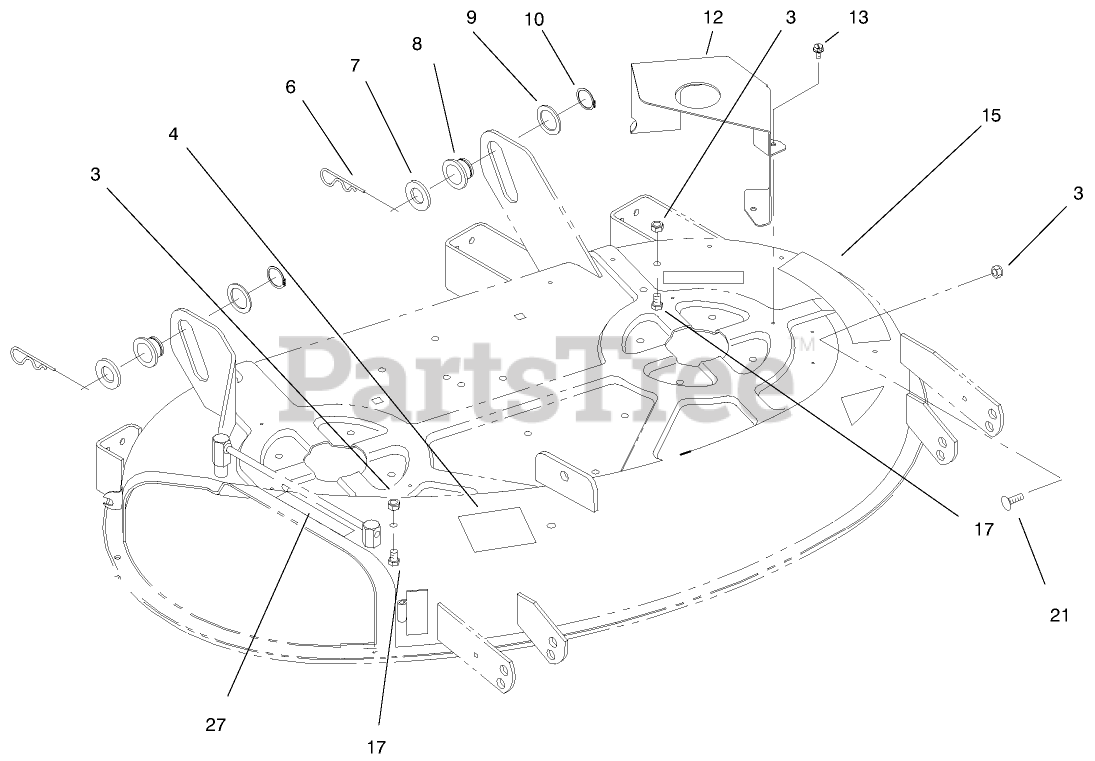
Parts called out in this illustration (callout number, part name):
3	NUT-LOCK, NI
6	PIN-HAIR
7	WASHER-FLAT
8	ROLLER-LIFT
9	WASHER-FLAT
10	RING-RETAINING
12	COVER-BELT
13	SCREW-HWHTF
15	Decal-Dange
17	SCREW-HH
21	SCREW-CARR
27	DECAL-CAUTION
